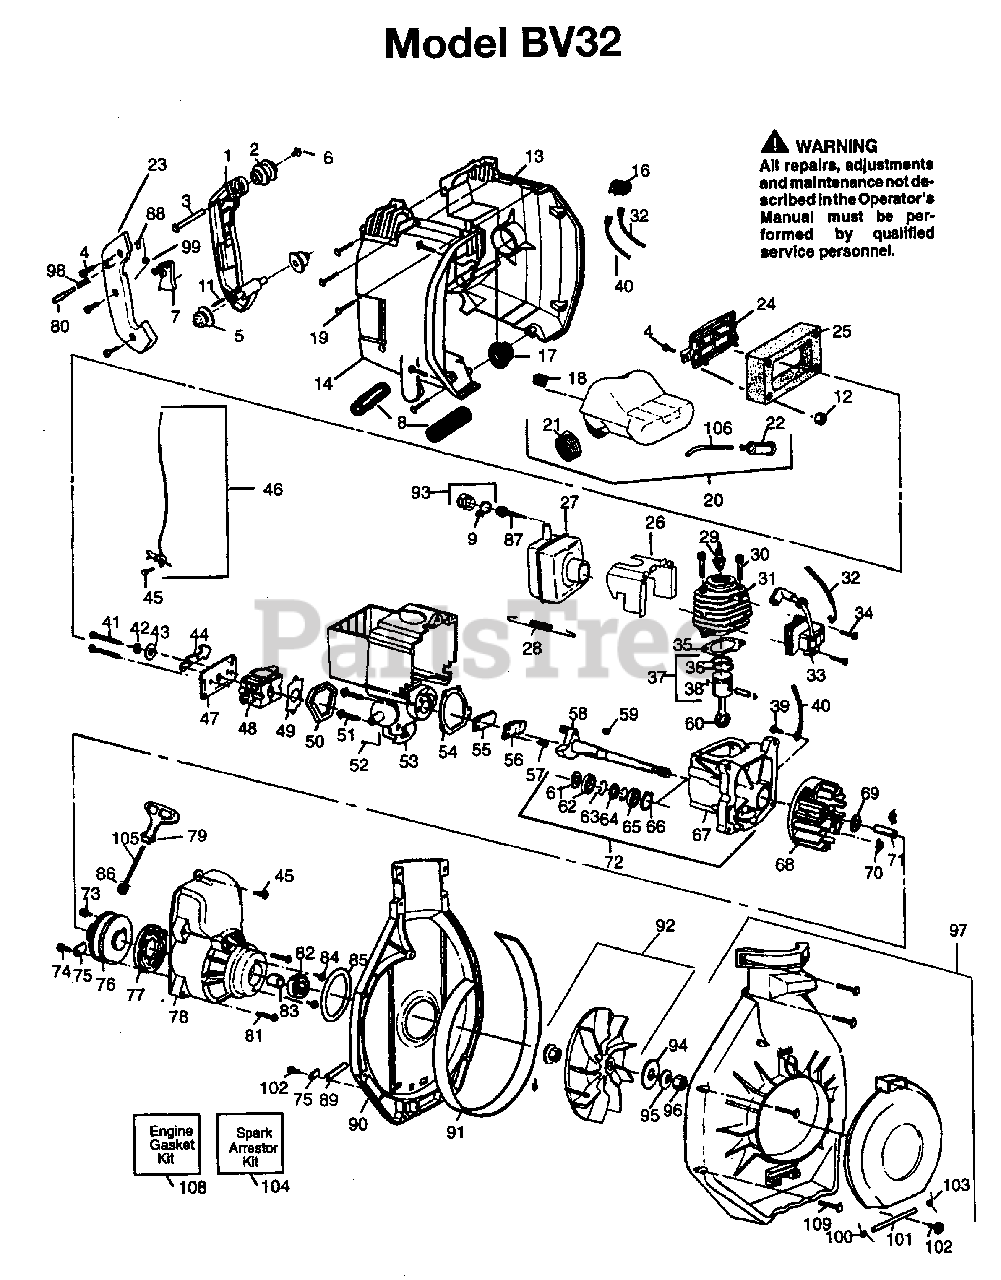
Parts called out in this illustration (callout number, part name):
1	HANDLE (BLACK)
3	SPACER-ISOLATOR
4	SCREW-10-14X5/8 PHIL.FI
5	ISOLATOR-HANDLE (REAR)
6	SCREW-10-24 X 3/8
9	CLAMP-SPARK ARRESTOR
11	HANDLE PIN
12	LOCKNUT - LINE LIMITER
17	ISOLATOR-ENGINE MOUNT
18	ISOLATOR-TANK
20	ASSY-FUEL TANK W/RETAIN
21	CAP ASSY W/ RETAINER
22	FUEL PICK UP ASSY
23	ASSY-COVER & THROTTLE LOCK
25	AIR FILTER
26	AIR BAFFLE
28	SPRING-MUFFLER
29	SPARK PLUG (RCJ-8Y) NLA
30	SCREW 1/4-20 X 7/8
31	CYLINDER
33	IGNITION MODULE.
34	SCREW 8-32 X 3/4
35	GASKET-CYL W/ADHESIVE
36	RING-PISTON (HOOKED)
37	KIT-PISTON (32CC)
38	WRIST PIN RET.
39	SCREW(10-24 X 7/16 HEX
43	CHOKE SPACER
44	SHUTTER-CHOKE
45	SCREW 8-16 X 9/16 (PLAS
46	THROTTLE CABLE
47	PLATE-AIR FILTER MTG
48	CARB ASS'Y WT-141A
49	GASKET-CARB
50	SEAL-FOAM/REED BLOCK
51	SCREW 1/4-20 X 7/8 (TAP
52	WIRE-GROUND/STATIC
53	REED BLOCK/HEAT SHIELD
54	GASKET-REED BLOCK/C'CAS
55	VALVE-REED
56	REED STOP
58	ASSY-CRANKSHAFT
59	KEY-FLYWHEEL
60	ASS'Y-CONNECTING ROD
61	SPACER-BEARING
62	BEARING-R8 (INNER)
63	RING-RETAINING
64	SEAL-CRANKSHAFT
65	BEARING-R8 (OUTER)
66	RING-RETAINING (SHAFT)
67	ASSY-CRANKCASE
69	WASHER
70	SPRING STR DOG
71	SPACER-FLYWHEEL
72	ASSY-C'CASE & C'SHAFT
74	SCREW-10-16 X 1/2 HI-LO
77	SPRING-STARTER
78	FAN HOUSING KIT
79	HANDLE-STARTER
80	BUTTON-THROTTLE LOCK
81	SCREW-10-24X1-3/8-TAPTI
82	BEARING-RADIAL BALL
83	SPACER-HUB
84	SCREW-10-14 X 13/16 (PL
85	O-RING SEAL
86	EYELET-FLANGE
87	SCREEN-SPARK ARRESTOR
88	C CLIP-THROTTLE LOCK
89	TUBE-ROPE RETAINER
90	HSG-BLOWER (UPPER) (BL)
91	BAND-BLOWER HSG
92	ASSY-IMPELLER
94	WASHER-IMPELLAR
95	WASHER CONICAL
97	BLOWER HOUSING ASSY - BLACK
98	SPRING-THROTTLE
99	SPRING-LEVER RETURN
100	SPRING-TORSION (RIGHT)
101	PIN-PIVOT
102	SCREW-10-16X1/2 HI-LO(S
103	SPRING-TORSION (LEFT)
104	SPARK ARRESTOR KIT
108	KIT-GASKET
109	SCREW
